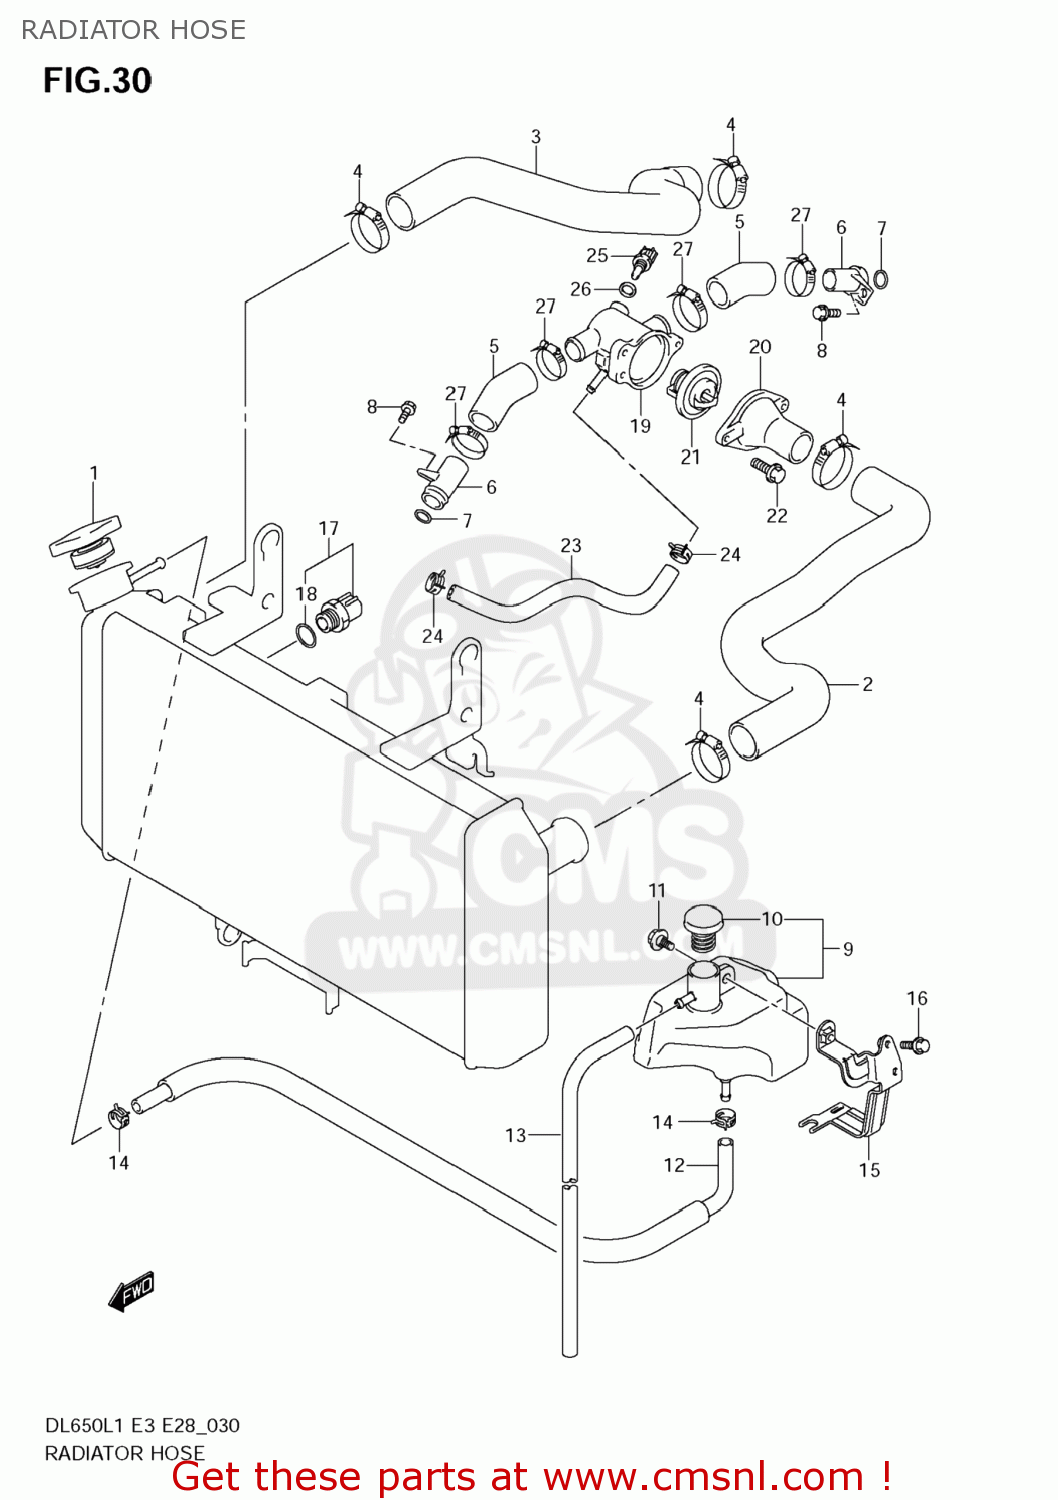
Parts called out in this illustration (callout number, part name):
1	CAP COMP,RADIATOR
2	HOSE,RADIATOR INLET
3	HOSE,RADIATOR OUTLET
4	CLAMP
5	HOSE,CONNECTOR INLET
6	UNION,CONNECTOR HOSE
7	O RING(D:3.2,ID:17.8)
8	BOLT
9	TANK ASSY,RESERVOIR
10	CAP,RESERVOIR TANK
11	BOLT(6X12)
12	HOSE SET,RESERVOIR TANK INLET
13	HOSE,RESERVOIR TANK OUTLET
14	CLIP
15	BRACKET,RESERVOIR TANK
16	BOLT
17	SWITCH,FAN THERMO
18	O-RING
19	CONNECTOR,THERMOSTAT INLET
20	CAP,THERMOSTAT CONNECTOR
21	THERMOSTAT,WATER
22	BOLT
23	HOSE,CONNECTOR TO WATER PUMP
24	CLAMP
25	SENSOR,WATER TEMP
26	GASKET(12X17X1) (NAS)
27	CLAMP
